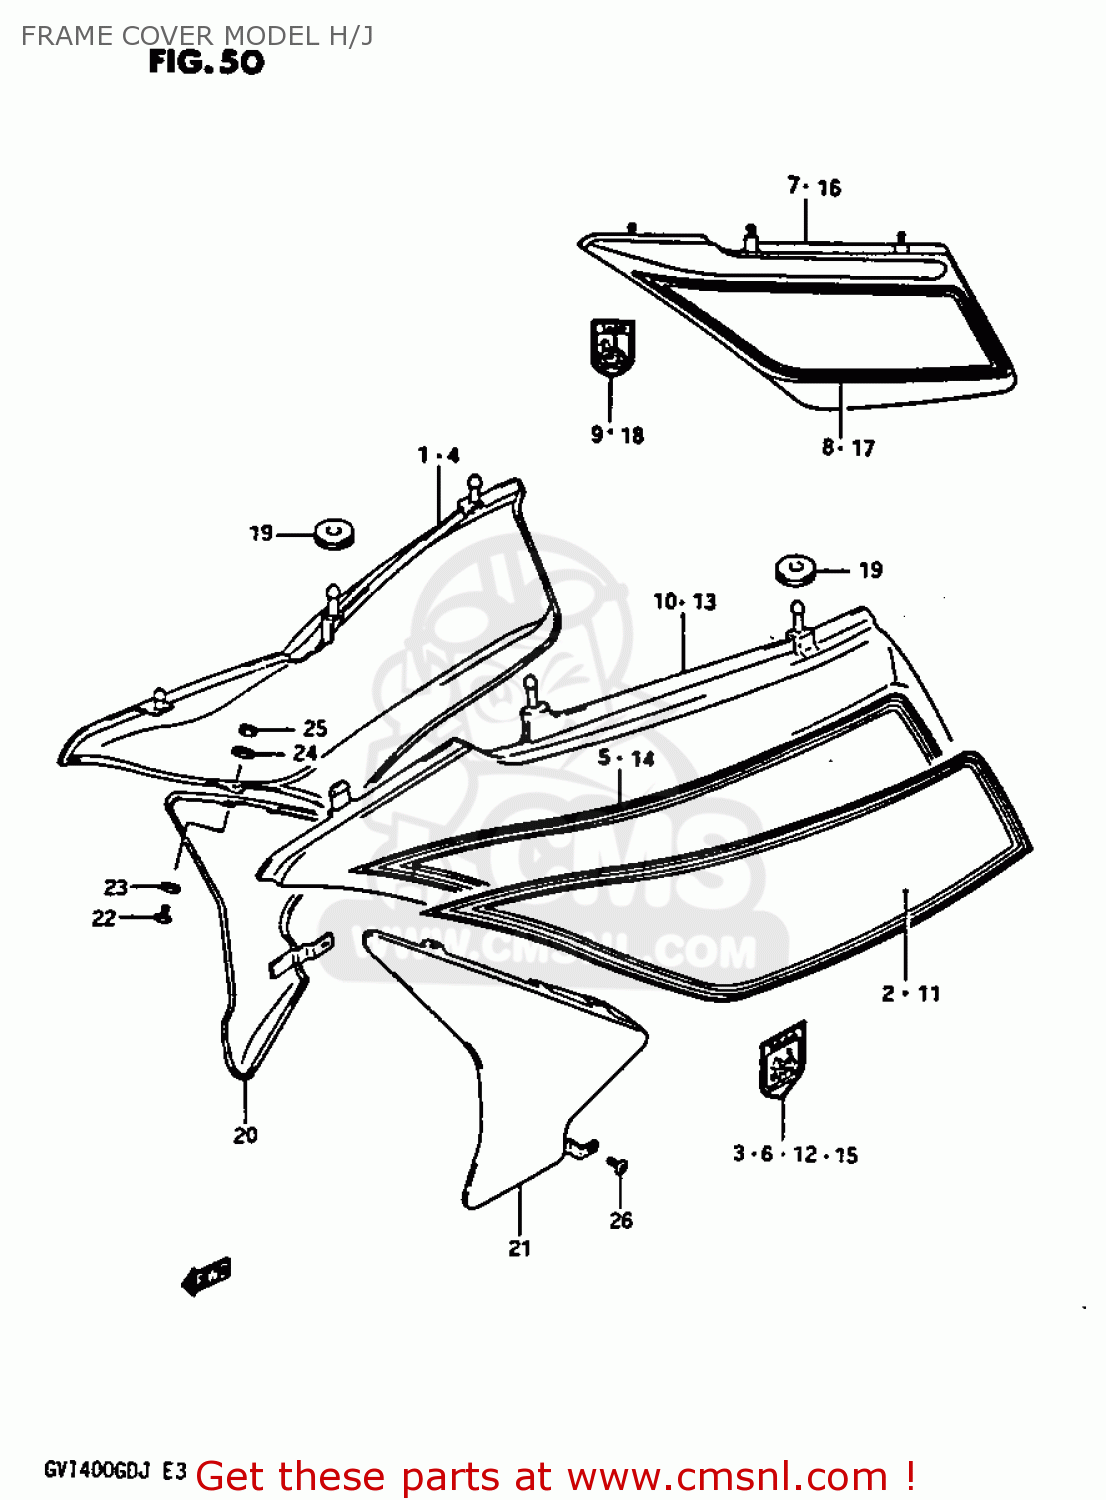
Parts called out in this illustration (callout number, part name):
1	COVER,FRAME,RIGHT
2	TAPE SET,FRAME COVER
3	EMBLEM,FRAME COVER
4	COVER,FRAME,RIGHT
5	TAPE SET,FRAME COVER
6	EMBLEM,FRAME COVER
7	COVER,FRAME,RIGHT
8	TAPE SET,FRAME COVER
9	EMBLEM,FRAME COVER
10	COVER,FRAME,LEFT
11	TAPE SET,FRAME COVER
12	EMBLEM,FRAME COVER
13	COVER,FRAME,LEFT
14	TAPE SET,FRAME COVER
15	EMBLEM,FRAME COVER
16	COVER,FRAME,LEFT
17	TAPE SET,FRAME COVER
18	EMBLEM,FRAME COVER
19	CUSHION
20	COVER,UNDER,RIGHT
21	COVER,UNDER,LEFT
22	SCREW
23	WASHER
24	WASHER (6.7X16X1.8)
25	NUT 6MM
26	SCREW
